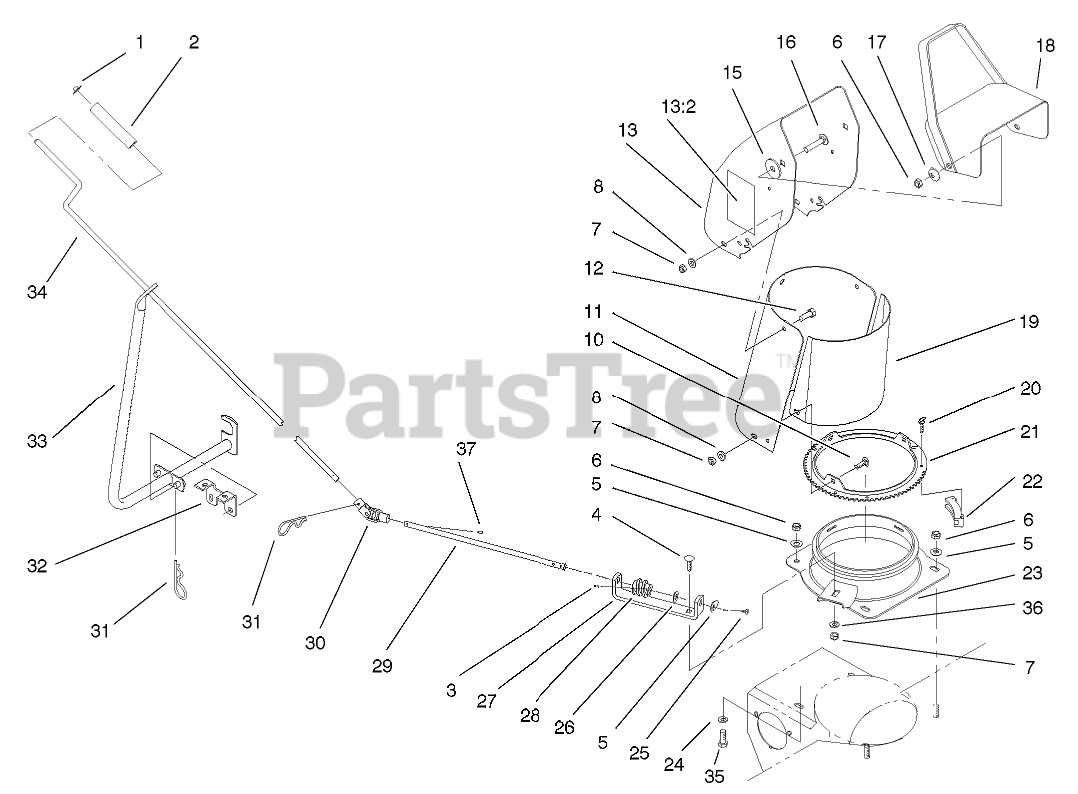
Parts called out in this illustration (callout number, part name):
1	RETAINER-PUSH ON
2	GRIP-CONTROL, CHUTE
3	PIN-SPRING
4	BOLT-CARR
5	WASHER-FLAT
6	NUT-LOCK, NI
7	NUT-LOCK, NI
8	WASHER-PLAIN
10	BOLT-CARR
11	EXTENDER-CHUTE, UPPER
12	SCREW-HH
13	CHUTE
13:2	DECAL-DANGER (only on: 38078)
15	WASHER-RUBBER
16	BOLT-CARR
17	WASHER-BELLEVILLE
18	DEFLECTOR
19	SHIELD-DEFLECTOR
20	SCREW-SPECIAL
21	CHUTE SWIVEL RING
22	RETAINER-CHUTE
23	ADAPTER
24	WASHER-SPACER
25	PIN-COTTER
26	WASHER-SPRING
27	BRACKET-WORM
28	GEAR-WORM, CHUTE
30	JOINT-UNIVERSAL
31	PIN-HAIR
32	BRACKET
33	SUPPORT
34	ROD-CHUTE CONTROL
35	SCREW-HH
36	WASHER-LOCK
37	PIN-SPRING
